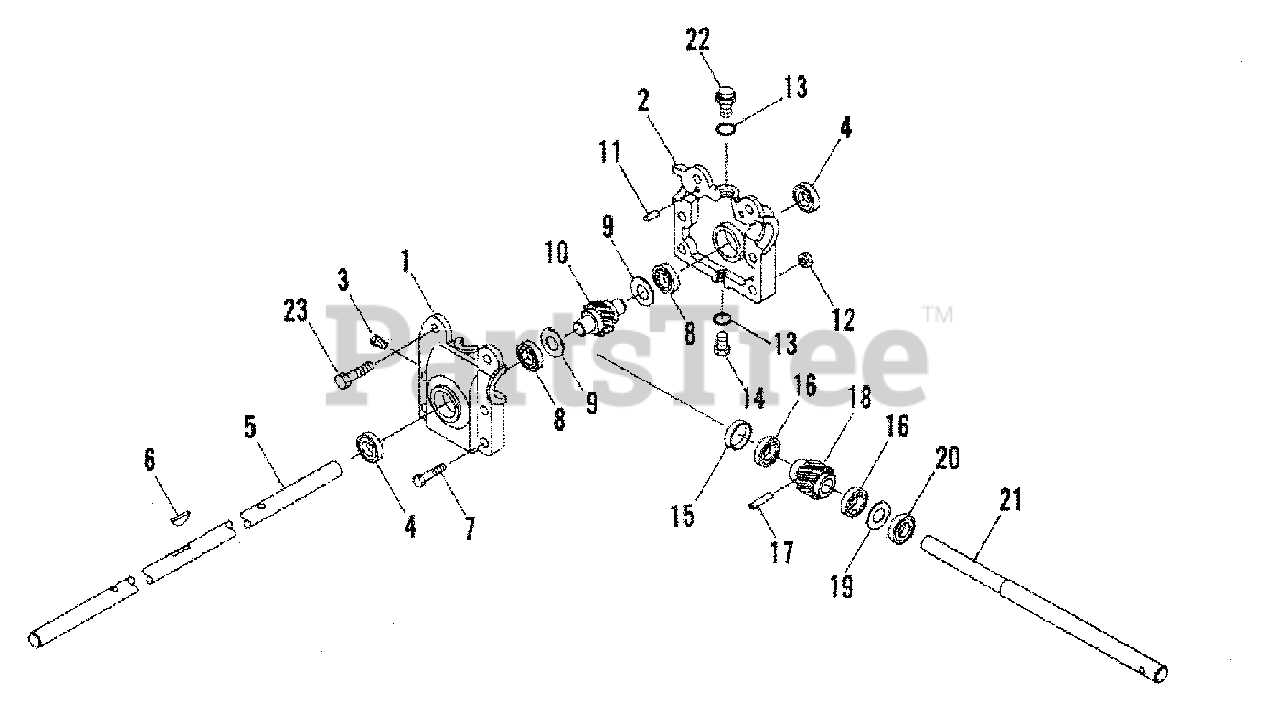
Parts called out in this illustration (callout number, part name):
1	Casing L.H.
2	Casing R.H.
3	Plug - 1/4
4	Seal - Double Lip
5	Output Shaft
6	Key - Woodruff #91
7	Bolt - Hex, M8 x 65
11	Pin - Spring
12	Nut - Hex, M8
17	Spring Pin
18	Pinion Shaft
21	Shaft - Input
22	Plug - 3/8
23	Bolt - Hex, M8 x 40
